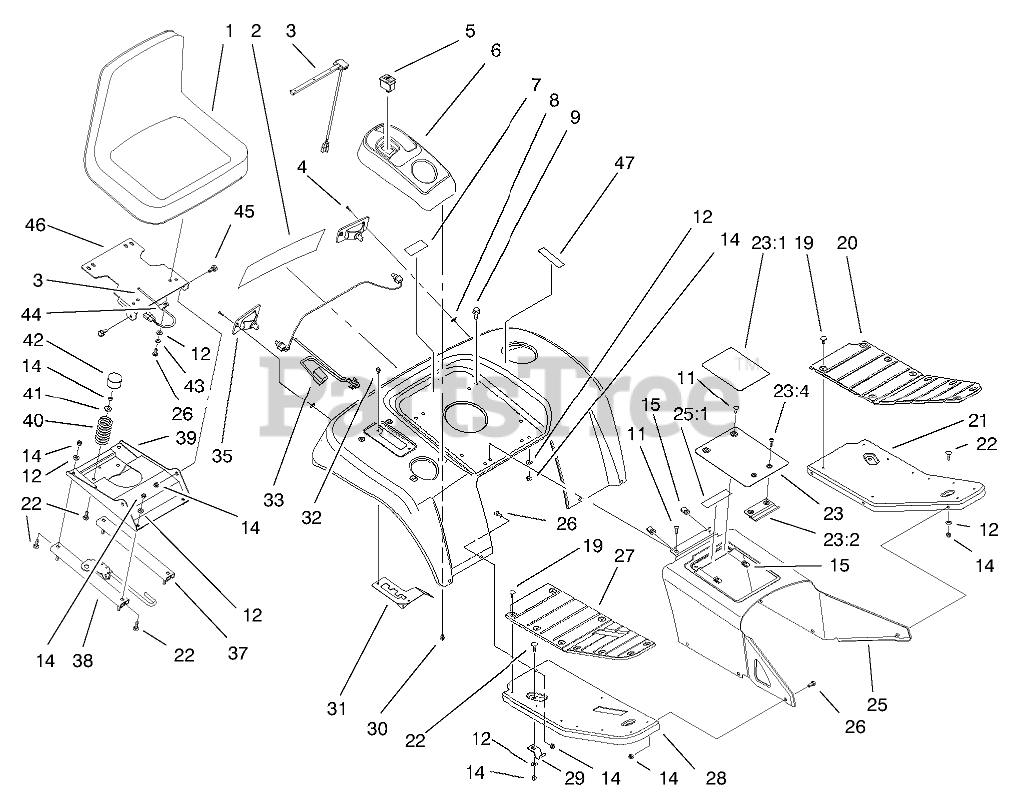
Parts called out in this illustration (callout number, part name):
1	SEAT
2	DECAL - FENDER
3	SWITCH-SEAT
4	SCREW-PPH
5	SWITCH-CRUISE
6	Pod-Control (Only On: 73550)
6	Pod-Control (Only On: 73551)
7	Decal-USA (Only On: 73550)
8	NUT-SPEED
9	SCREW-HHF
11	SCREW-HH
12	WASHER-PLAIN
14	NUT-LOCK, NI
19	FASTENER-PANEL
20	PAD-FOOTREST, LH
21	FOOTREST-LH
22	SCREW-CARR
23	Tunnel Cover ASM (Only On: 73550)
23	Tunnel Cover ASM (Only On: 73551)
23:1	Decal-Danger (Only On: 73550)
23:1	Decal-Danger (Only On: 73551)
23:2	RETAINER-COVER
23:4	SCREW-PPH
25	Tunnel ASM (Only On: 73550)
25	Tunnel ASM (Only On: 73551)
25:1	Decal-Danger (Only On: 73550)
25:1	Decal-Warning (Only On: 73551)
26	SCREW-HH
27	PAD-FOOTREST, RH
28	FOOTREST-RH
29	BRACKET-FOOTREST
30	SCREW-HHFTF
31	Gate-Hi Lo Shift
32	SCREW-HWH
33	HARNESS - REAR
35	LAMP-TAILLIGHT
37	SLIDE-SLAVE, SEAT
38	SLIDE-LATCH, SEAT
39	Base-Seat
40	SPRING-COMPRESSION
41	BUSHING
42	CAP-SPRING, SEAT
43	WASHER-LOCK
44	CLAMP-R
45	BOLT-SHOULDER
46	Mount-Seat
47	DECAL - DIESEL
